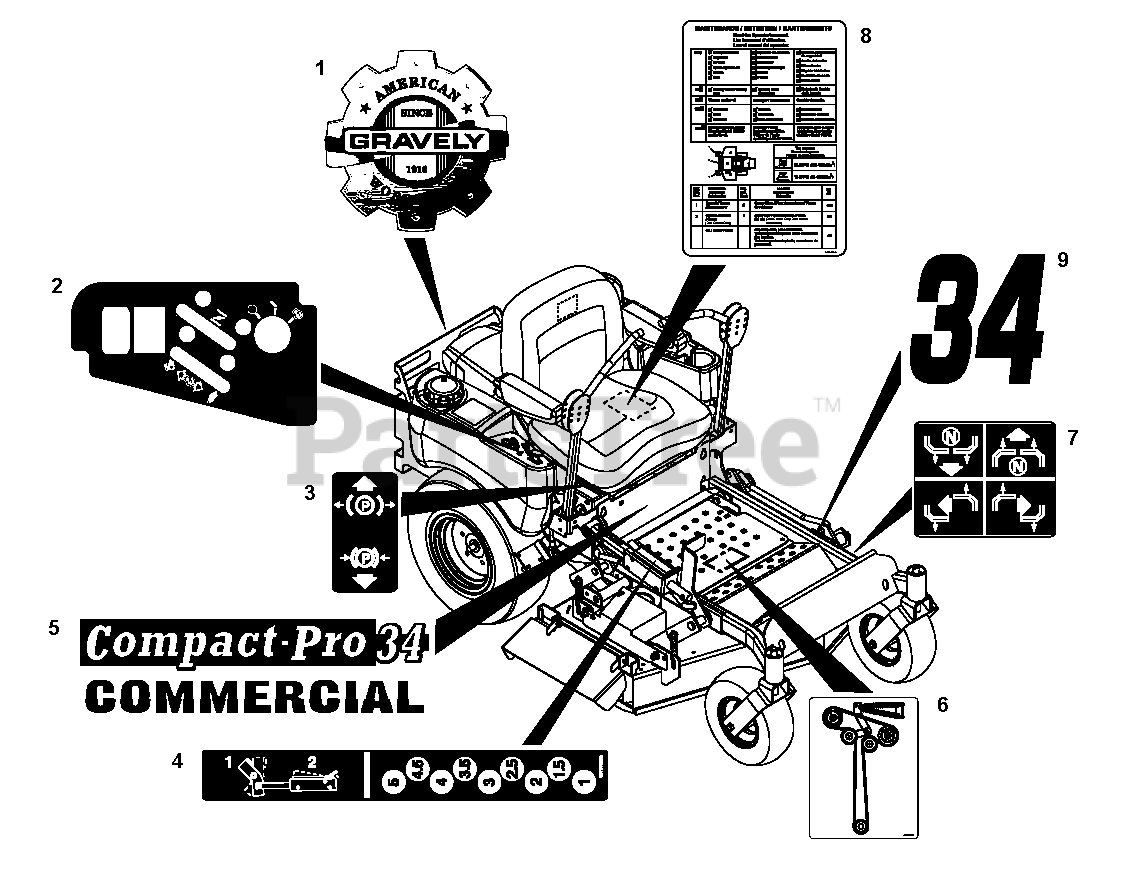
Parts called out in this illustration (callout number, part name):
1	Decal, Heritage Large
2	Decal, Control Panel
3	Decal, Parking Brake Lever
4	Decal, Height of Cut
5	Decal, Compact-Pro 34
6	Decal, Belt Diagram
7	Decal, Instructional Steering
8	Decal, Maintenance Instructions
9	Decal, 34"
